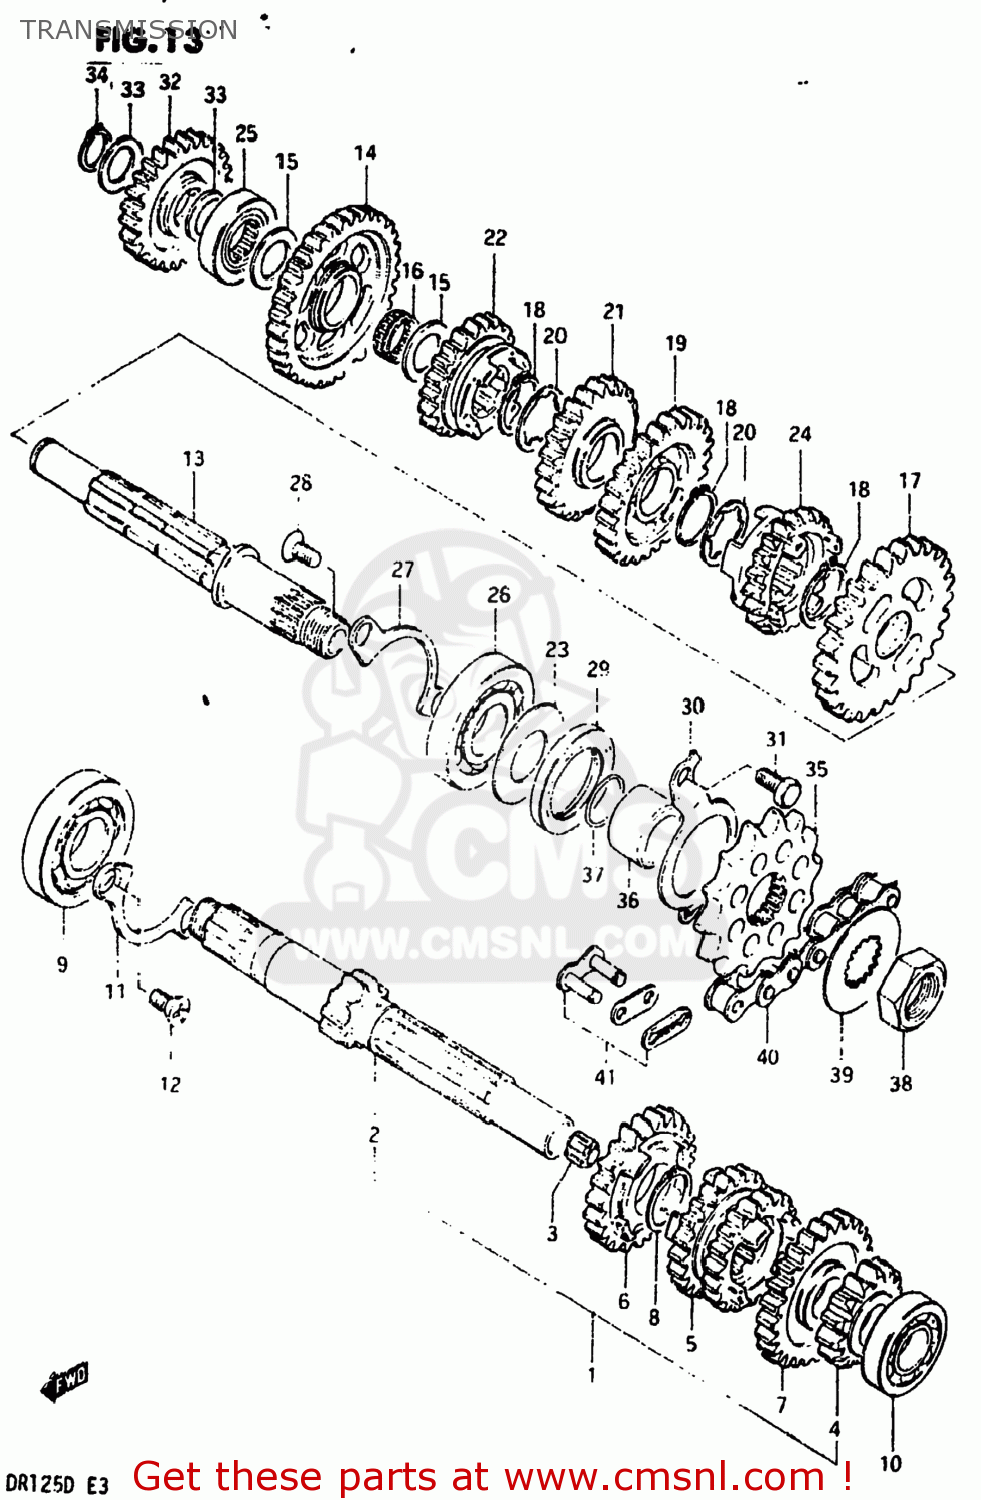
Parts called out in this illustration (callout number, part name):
1	SHAFT,COUNTER
2	SHAFT,COUNTER
3	BUSHING
4	GEAR,SECOND DRIVE
5	GEAR,THIRD & FOURTH DRIVE,N
6	GEAR,FIFTH DRIVE
7	GEAR,SIXTH DRIVE
8	CIRCLIP
9	BEARING
10	BEARING, LH
11	RETAINER,DRIVE SHAFT BEARING
12	SCREW
13	SHAFT,DRIVE
14	GEAR,FIRST DRIVEN
15	WASHER
16	BEARING(15X19X7.8)
17	GEAR,SECOND DRIVEN
18	CIRCLIP
19	GEAR,THIRD DRIVEN
20	WASHER,LOCK
21	GEAR,FOURTH DRIVEN
22	GEAR,FIFTH DRIVEN
23	WASHER,OIL SEALING
24	GEAR,SIXTH DRIVEN
25	BEARING(15X33X12)
26	Bearing
27	RETAINER,DRIVE SHAFT BEARING
28	SCREW
29	SEAL,OIL(27X40X6)
30	PLATE,DRIVESHAFT OIL
31	BOLT
32	GEAR,KICK STARTER IDLE
33	WASHER
34	CIRCLIP,15MM
35	SPROCKET,ENGINE
36	SPACER
37	O RING(D:2.4,ID:19)
38	NUT
39	WASHER,LOCK
40	CHAIN ASSEMBLY,DRIVE
41	JOINT SET,CHAIN
